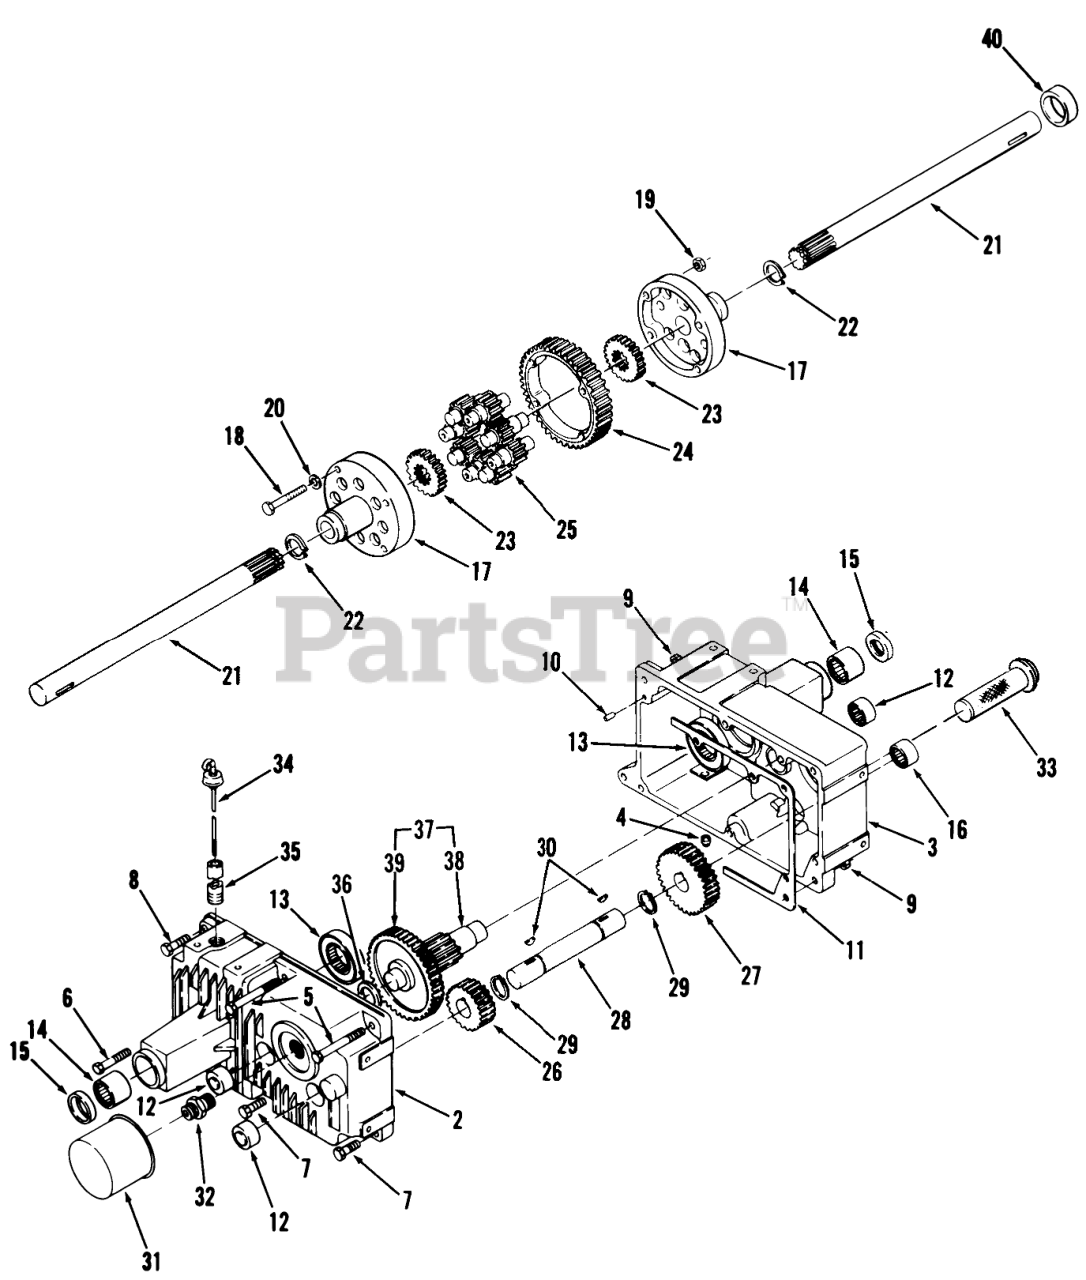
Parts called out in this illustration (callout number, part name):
1	Assy-Transaxle
2	Case RH
3	Case LH
4	PLUG 1/4 PIPE ALLEN
5	H H C S
6	HHCS
7	Bolt
8	Bolt
9	Nut
10	PIN-DOWEL
11	GASKET
12	BEARING-NEEDLE
13	NEEDLE BEARING
14	BEARING
15	SEAL-OIL
16	Needle Bearing
17	DIFFERENTIAL END CAP
18	BOLT-HEX
19	Nut
20	WASHER
21	REAR AXLE
22	SNAP RING
23	GEAR-AXLE DIFFERENTIAL
24	GEAR-DIFFERENTIAL RING, 43T
25	GEAR-PINION, 11T
26	20T GEAR
27	Gear 44T
28	SHAFT GEAR
29	Snap Ring
30	Key
31	Filter
32	FITTING
33	STRAINER
34	Dipstick
35	Nipple
36	WASHER-THRUST
38	PINION SHAFT
39	GEAR 46T
40	RACE BEARING
